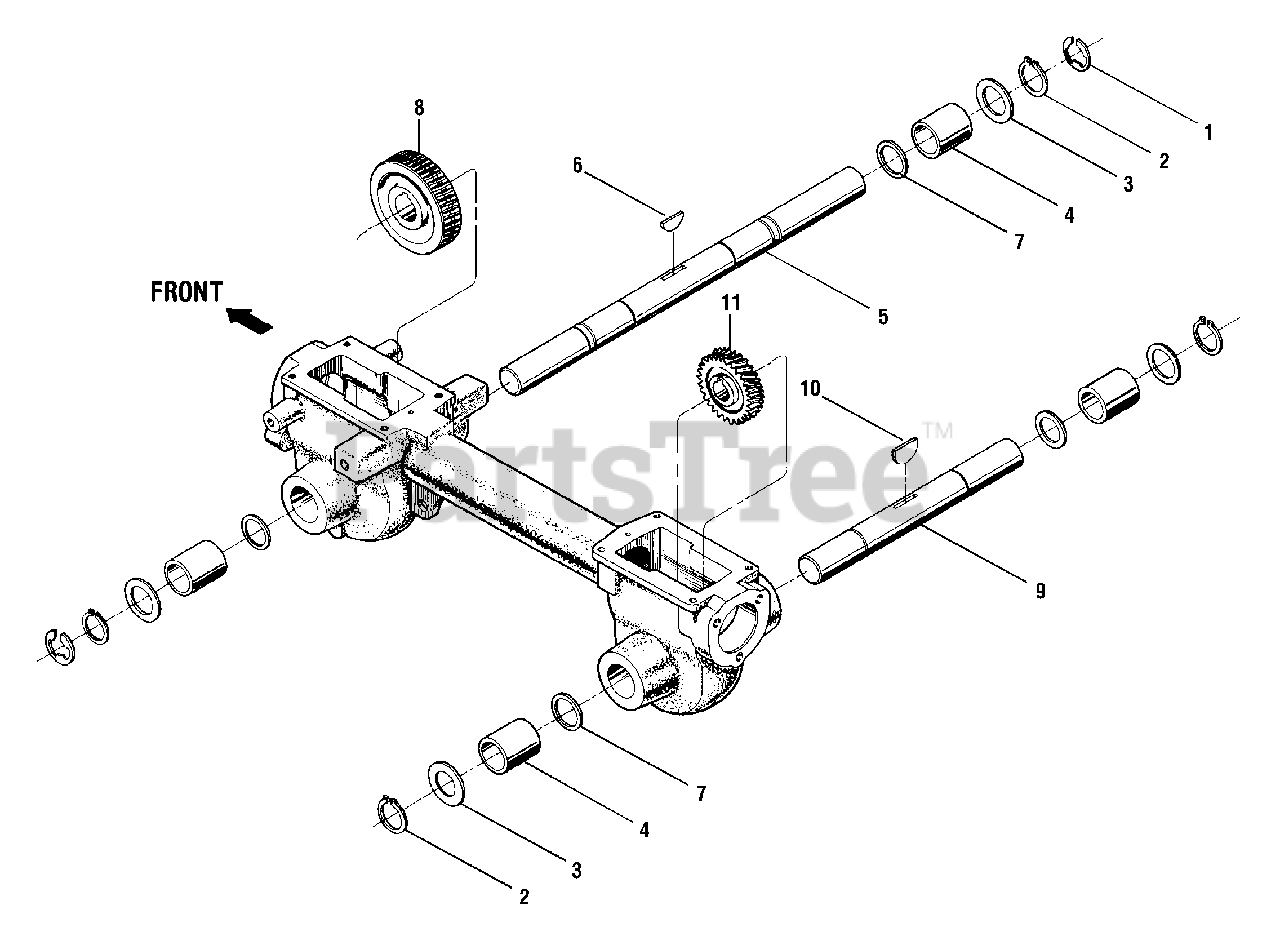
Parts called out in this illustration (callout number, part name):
1	Retainer, Snap Ring, "E" Type
2	Retainer, Snap Ring
3	Shim, 0.062" thick
4	Bronze Bushing
5	Wheel Shaft
6	Key, Hi-Pro, 1/4 x 1
7	Spacer
8	Worm Gear, Wheel Shaft
9	Tiller Shaft
10	Woodruff Key
11	Worm Gear, Tiller Shaft
